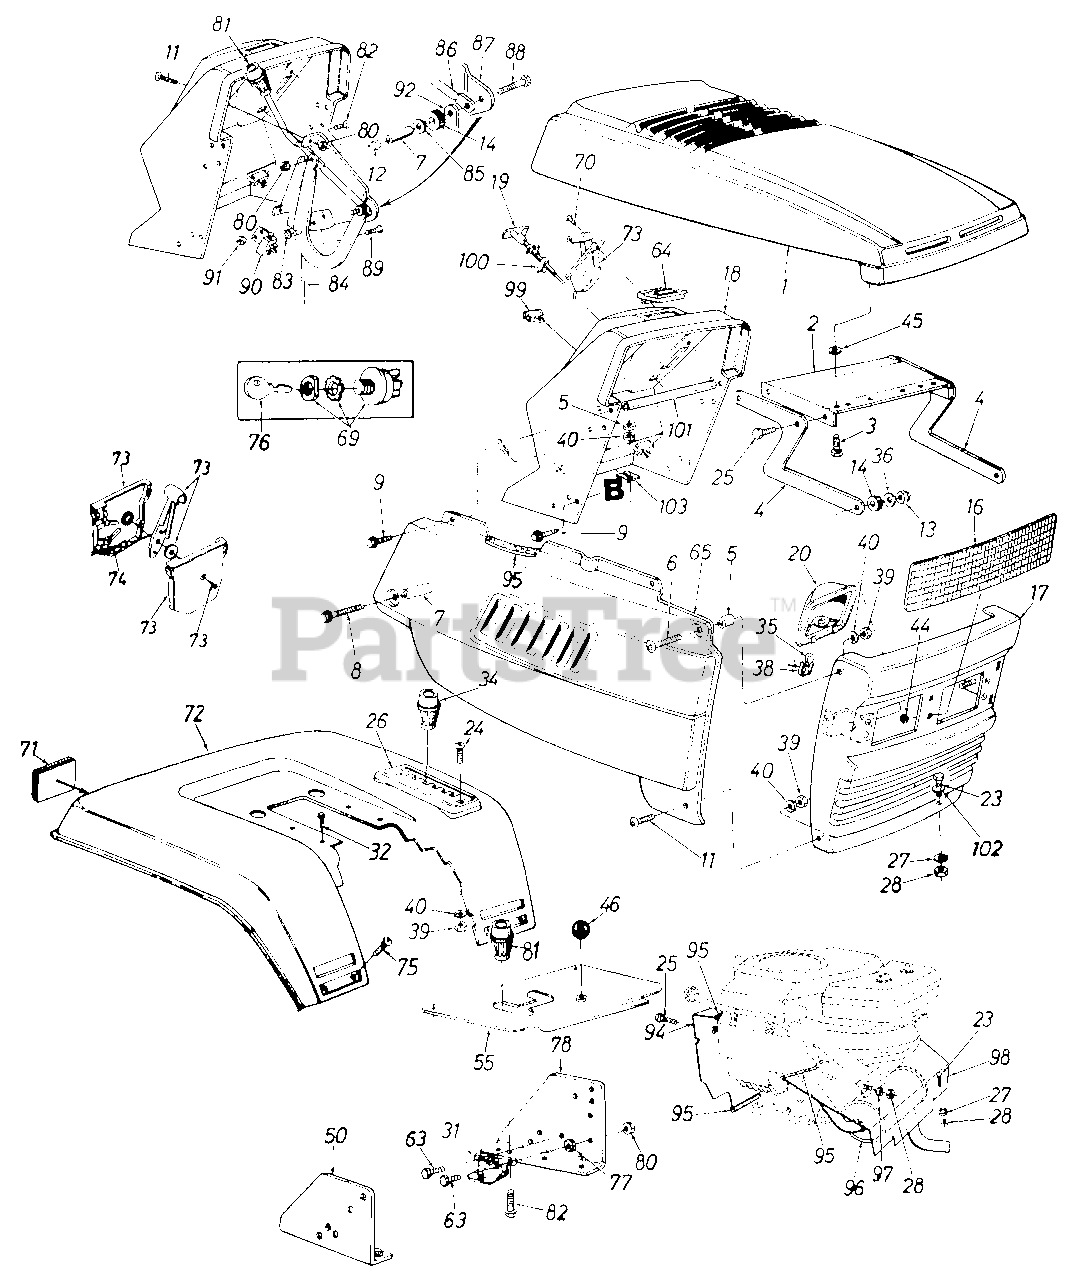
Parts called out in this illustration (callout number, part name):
1	Hood (Red)
6	Truss Hd. Mach. Scr. 1/4-20 Thd.
7	Spacer .26" I.D. x .375"
8	Hex Wash. TT-Tap Scr. 1/4-20 x 1.75" Lg.
9	Hex T-Tap Scr. 1/4-20 x .75" Lg.
11	Truss Mach. Scr. 1/4-20 x .5" Lg.
12	Hex Ins. L-Nut 1/4-20 Thd.
13	Hex L-Nut 5/16-18 Thd.
14	Rubber Washer
16	Headlight Lens
19	Choke Control
20	Headlight Housing
23	Hex Bolt 5/16-18 x .75" Lg.
24	Truss Mach. Scr. 1/4-20 x .75" Lg.
25	Hex Wash. Hd. Scr. 1/4" x .5" Lg.
26	6-Speed Selector Plate
27	L-Wash. 5/16" I.D.
28	Hex Nut 5/16-18 Thd.
31	Solenoid
32	Hex Hd. Rolling Scr. 5/16-24 x .75" Lg.
34	Shift Knob
35	Lamp
36	Bell-Wash. .34" I.D. x .87"
38	Socket
39	Hex Nut 1/4-20 Thd.
40	L-Wash. 1/4" I.D.
44	Speed Nut 5/16" I.D.
45	Fl-Wash. .406" I.D.
46	Ball Knob
63	Hex Bolt 1/4-20 x .5" Lg.
64	Ammeter
70	Truss Mach. AB-Tap Scr. #10 x .5" Lg.
71	Reflector
74	Throttle Control Wire 35" Lg.
75	Carriage Bolt 1/4-20 x .5" Lg.
76	Key
77	Ext. L-Wash. 1/4" I.D.
81	Knob
82	Hex Bolt 1/4-20 x .62" Lg.
83	Push Nut
84	PTO Rod
85	Fl-Wash. .281" I.D. x .73"
86	PTO Lever
87	Deck Clutch Control Brkt.
88	Hex Bolt 1/4-20 x 2.5" Lg.
89	Truss Mach. Scr. #10-24 x .5" Lg.
90	Safety Switch
91	Hex Nut #10-24 Thd.
92	PTO Bracket
94	Engine Baffle
95	Trim Strip 12" Lg.
96	Muffler
97	Spec. L-Wash .5/16" I.D.
98	Front Heat Shield
99	Light Switch
100	Retainer Clip
101	Dash Support Tube
102	Fl-Wash. .344" I.D. x 1" O.D.
103	Dash Panel Fastening Tab
